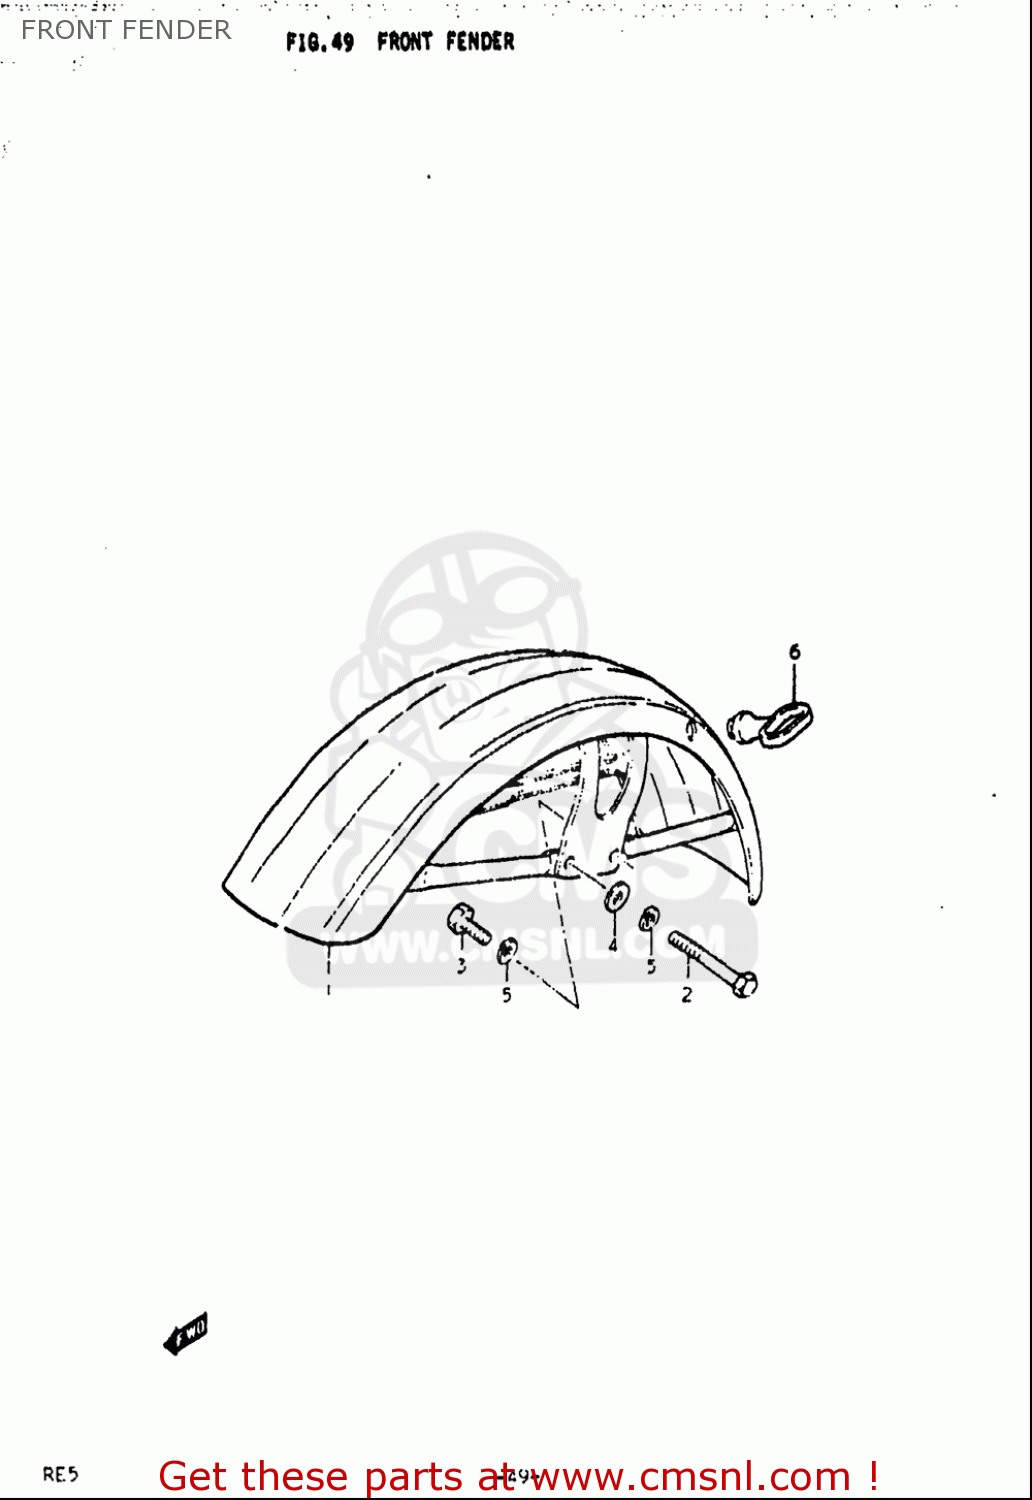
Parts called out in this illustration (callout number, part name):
2	BOLT
4	WASHER
5	WASHER,LOCK
6	GUIDE,CABLE
